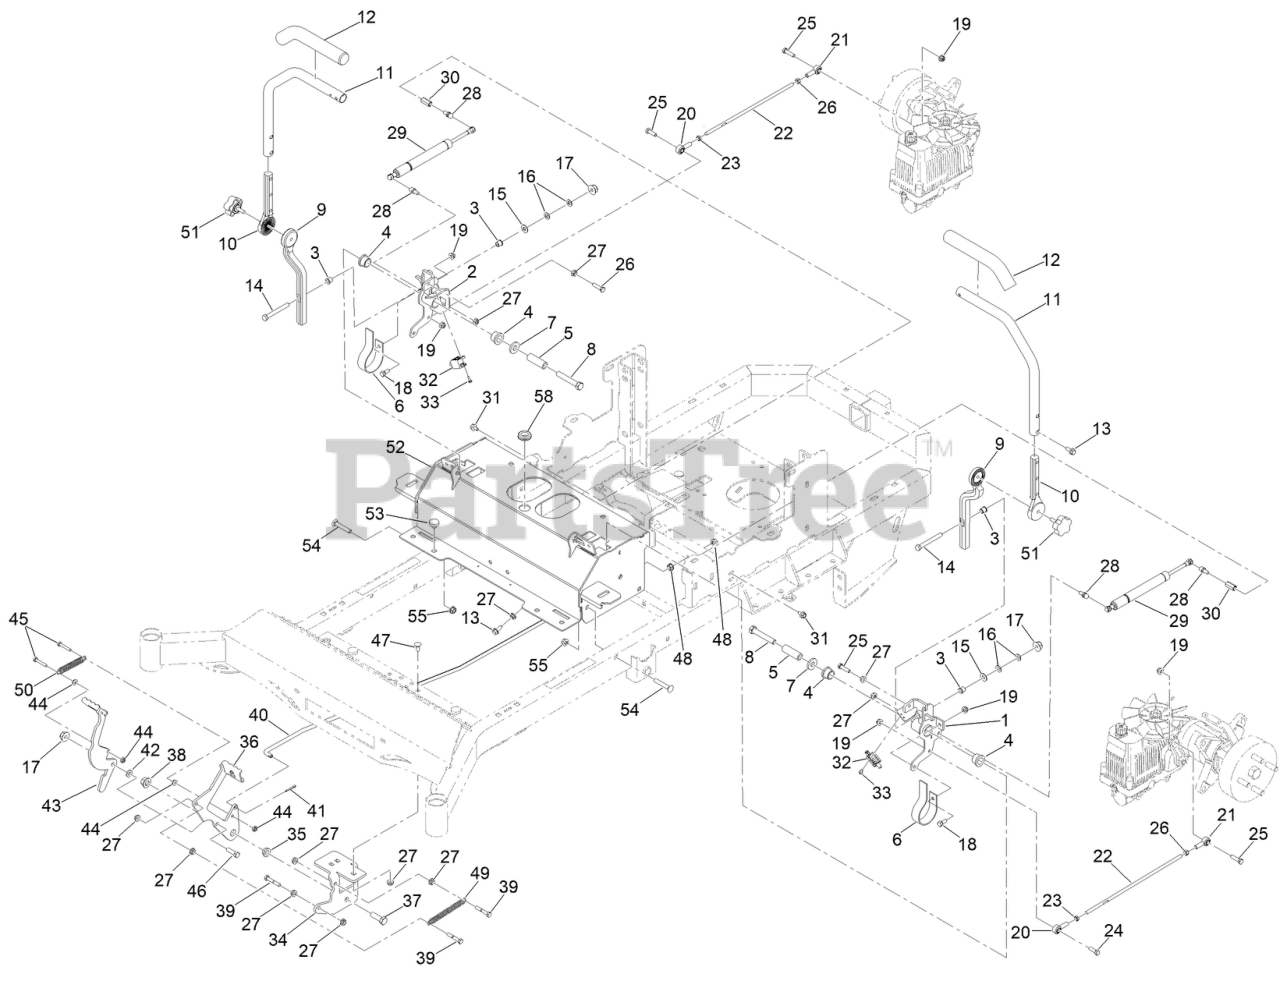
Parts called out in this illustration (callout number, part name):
1	LH PIVOT ASM
2	RH PIVOT ASM
3	BUSHING-FLANGE
4	BUSHING-FLANGE
5	SLEEVE-PIVOT
6	SPRING-LEAF
7	1/2 FENDER WASHER 1-1/4IN OD ZINC
8	1/2-13 X 3 HEX C/S GR 5 ZINC W/LOCTITE
9	ADJUSTABLE LWR DRIVE ARM
10	ADJUSTABLE UPP DRIVE ARM
11	MOWER DRIVE HANDLE TUBE ABC
12	CONTROL ARM HANDLE GRIP
13	SCREW-HHF
14	SCREW-HH
15	WASHER-FLAT
16	WASHER-BELLEVILLE
17	3/8-16 NYLON INSERT FLANGE L/NUT YZ
18	SCREW-HH
19	NUT-HF, NI
20	5/16-24 SPHER ROD END ZINC LH THD FEM
21	5/16-24 SPHER ROD END ZINC RH THD FEM
22	1310 TTQ DRIVE ARM ROD
23	NUT-JAM
24	SCREW-HH
25	SCREW-HH
28	5/16-18X1.286 DAMPER BALL STUD (.562 TL)
29	CONTROL ARM DAMPER
30	STANDOFF-HEX
31	SCREW-HHF
32	NO PLUNGER LIMIT SWITCH
33	8-32 X 1/2 IND. HWH SLOT TYPE F TCS ZINC
34	MWR FRAME BRAKE MTG BRKT PAINT
35	1/2IN ID X 3/4IN OD X 3/8IN FLANGE BUSH
36	MWR BRAKE LOCK LEVER ASSY PAINTED
37	SCREW-HH
38	NUT-LOCK
40	MWR BRAKE LINKAGE
41	PIN-COTTER
42	3/8 ID X 3/4 OD X .125 THK BRONZE WASHER
43	MWR BRAKE UNLOCK LEVER ASSY PAINTED
44	1/4-20 HEX FLANGE NUT
45	1/4-20 X 1-1/4 HEX C/S GR 2 ZINC
46	SCREW-HH
47	BOLT-CARR
48	3/8-16 HEX FLANGE NUT W/SERR ZINC YELLOW
49	2020 MWR BRAKE PEDAL TENSION SPRING
50	MWR BRAKE PEDAL RELEASE SPRING
51	5/16-18 X 1 SL 5-LOBE MALE ST KNOB 1.90
52	ASM, GT-TRAC [GRAY]
53	PUSH-IN RUBBER BUMPER MWR FLOOR
54	SCREW-CARR
58	GROMMET-RUBBER
